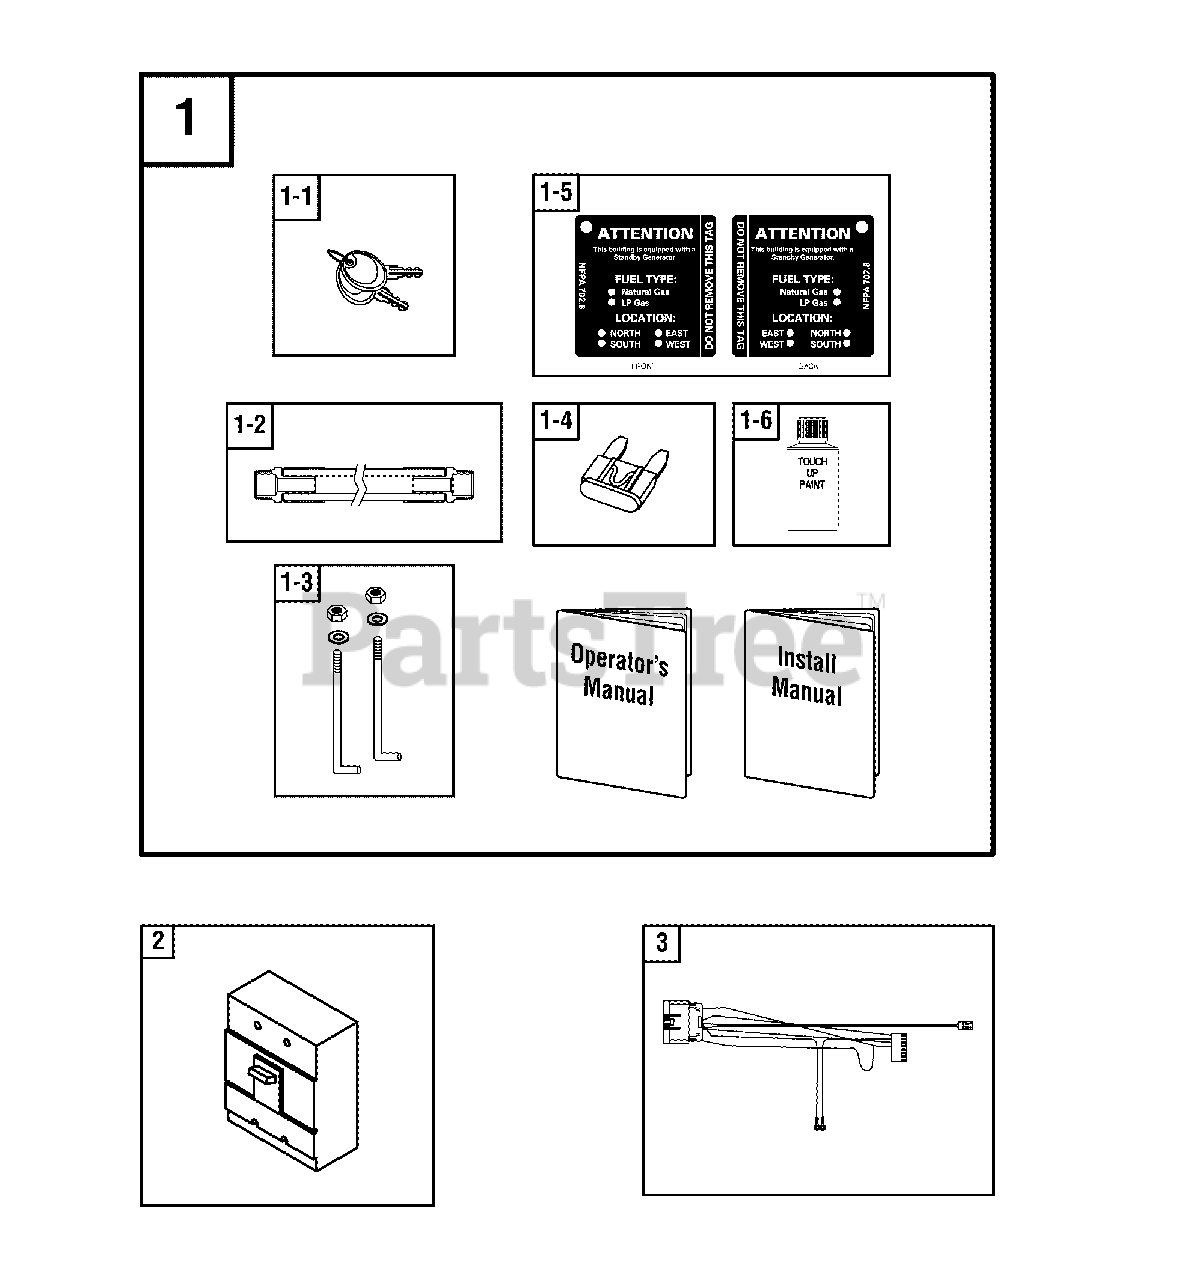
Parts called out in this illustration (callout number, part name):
1	KIT-MANUAL, ACC
1-3	KIT-HOLD DOWN, BATTERY
1-5	DECAL-ATTN STANDBY EQUIPMENT
1-6	PAINT-TOUCH-UP, ALMOND TEXTURE
2	BREAKER-CIRCUIT
